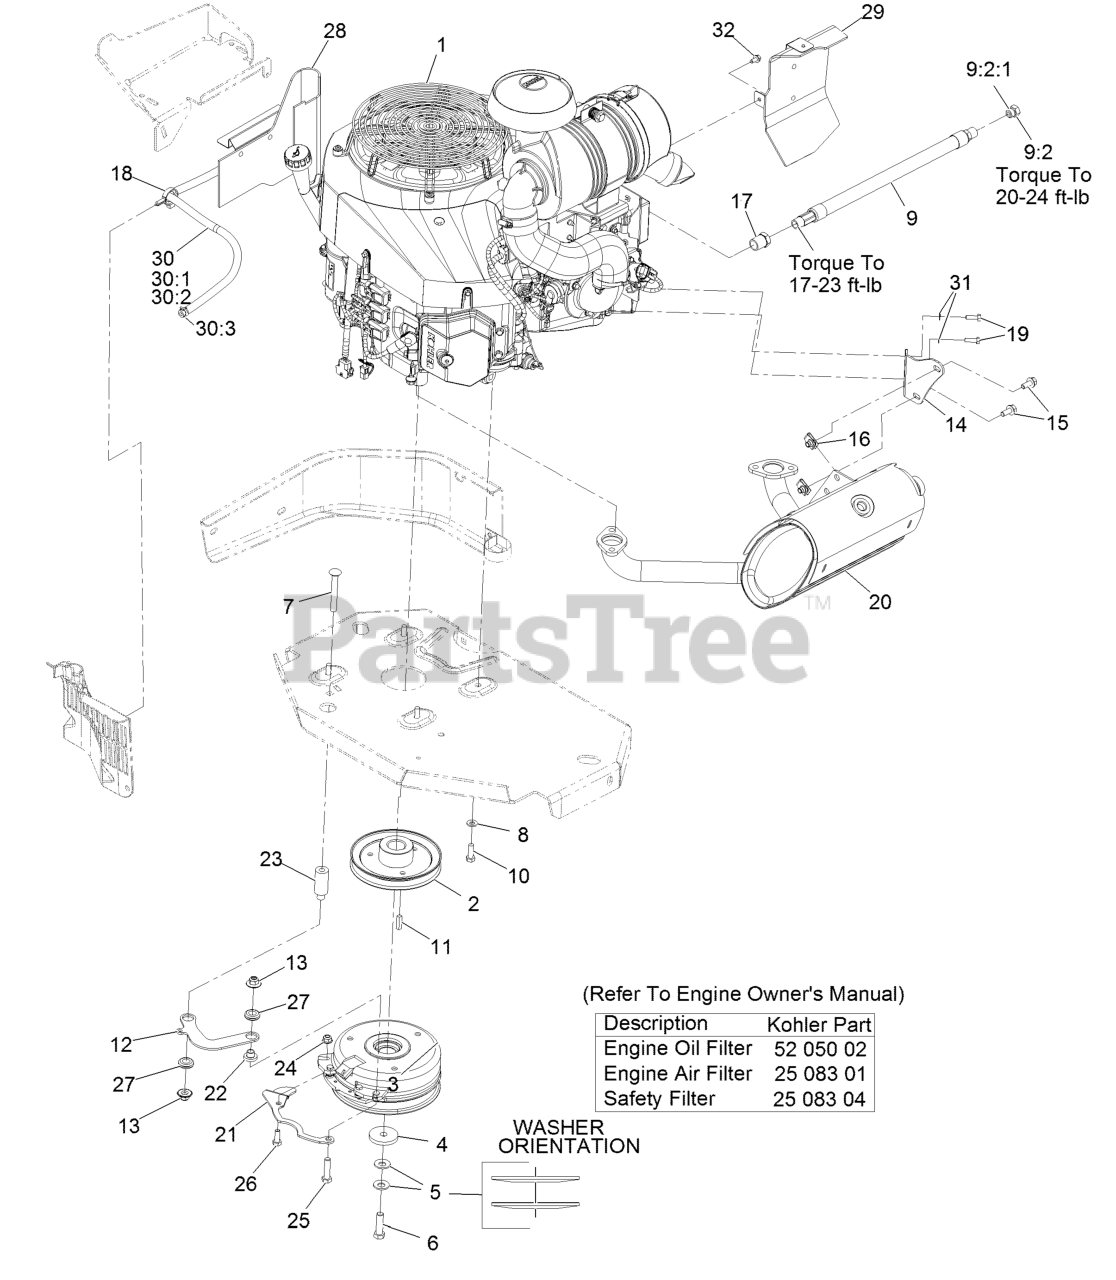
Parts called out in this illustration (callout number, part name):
1	Engine-Kohler, Ecv940 Efi-Egov
2	SHEAVE
3	CLUTCH KIT
4	WASHER-CLUTCH
5	WASHER-SPRING
6	SCREW-HH 7/16-20 X 1 1/2 W/LOCTITE
7	SCREW-CARR
8	WASHER-SPRING
9	OIL DRAIN HOSE ASM
9:2	PLUG-HH
9:2:1	O-RING
10	SCREW-HH
12	LINK-ANCHOR, CLUTCH
13	Nut-Nyloc 3/8-16 Flg
14	BRACKET-MUFFLER
15	SCREW-HHF
17	BUSHING
18	CLAMP-HOSE
19	SCREW-HH M6-1 X 20Mm W/Patch
21	BELT-GUIDE
24	NUT-HF, NI
25	SCREW-HH
26	SCREW-HH
27	GROMMET-RUBBER
28	BAFFLE-RH
29	BAFFLE ASM
30	FUEL LINE ASM
30:1	HOSE-FUEL
30:2	SLEEVE-THERMAL
30:3	CLAMP-HOSE
31	WASHER-SPRING
32	SCREW-HWH
